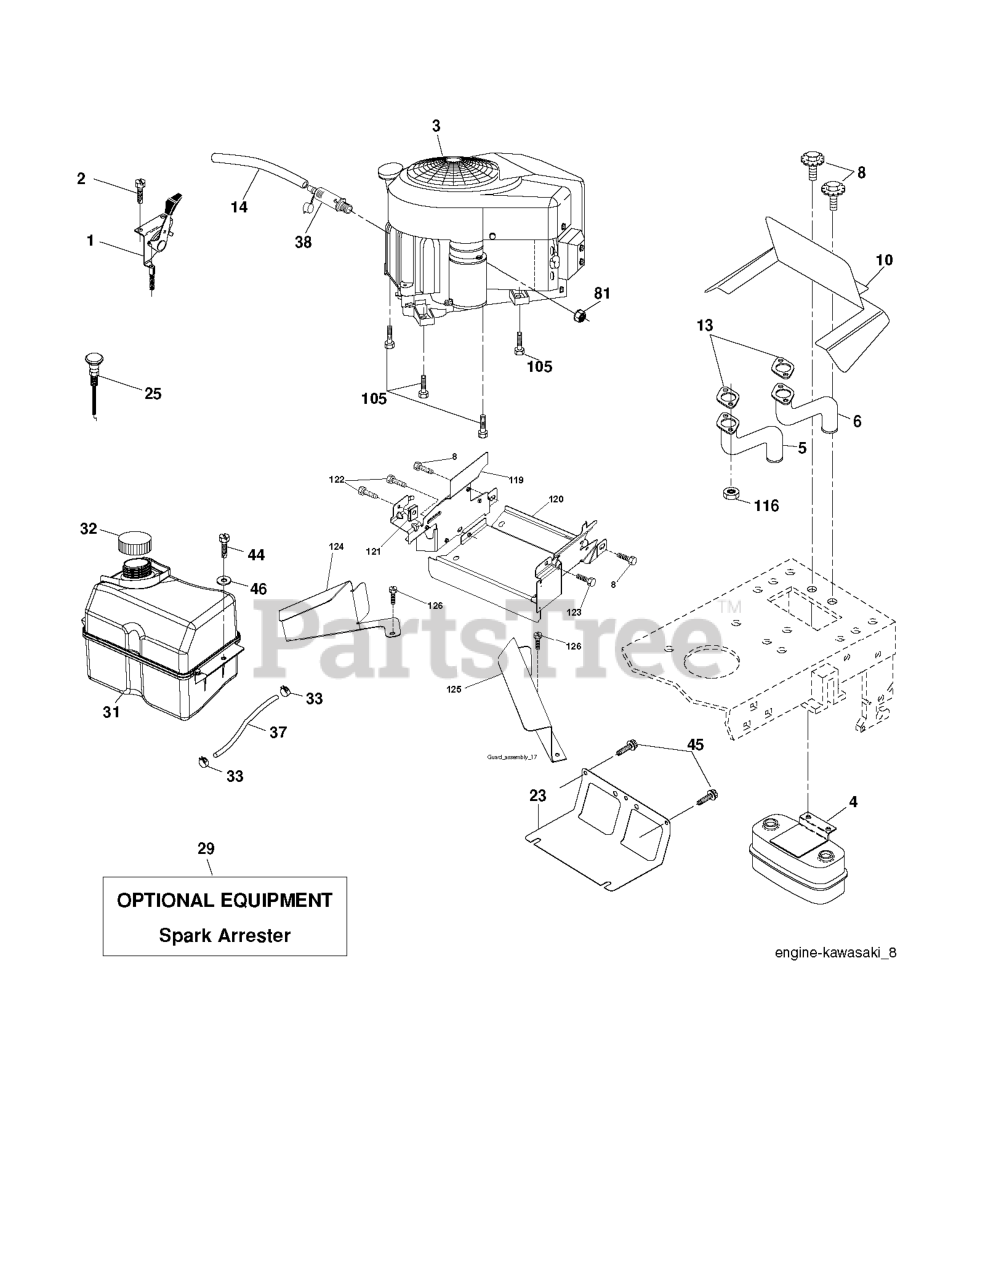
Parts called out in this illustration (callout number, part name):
1	CONTROL.THROTTLE.COBRA.BLACK
2	SCREW
4	MUFFLER.TWIN.CYL.LOW.TONE
5	EXHAUST TUBE LH KAWI
6	EXHAUST TUBE RH KAWI
8	BOLT.5/16-18UNCX3/4 W/SEMS.BLK
10	RP SHIELD HEAT MUFFLER
14	TUBE, DRAIN OIL ASM.
23	SHIELD.BROWNING.DBR.GUARD
25	CONTROL.CHOKE.ERGO.PUSH-IN.BLA
29	KIT.SPARK ARRESTOR 794945 B&S
31	RP TANK FUEL FRT 1.5 GAL
32	FUEL CAP
33	HOSE CLAMP
37	LINE.FUEL.20
44	SCREW HEXWSHR 1/4-20X3/4
45	SCREW, 3/8-16X3/4
46	WASHER
81	NUT
105	SCREW 3/8-16X1
116	NUT.HEX.FLANGE.TOPLOCK
119	LENKRAD
120	GUARD 532199767
122	SCREW.1/4-20X5/8
123	SCREW, 5/16-18 X 1/2
126	SCREW
